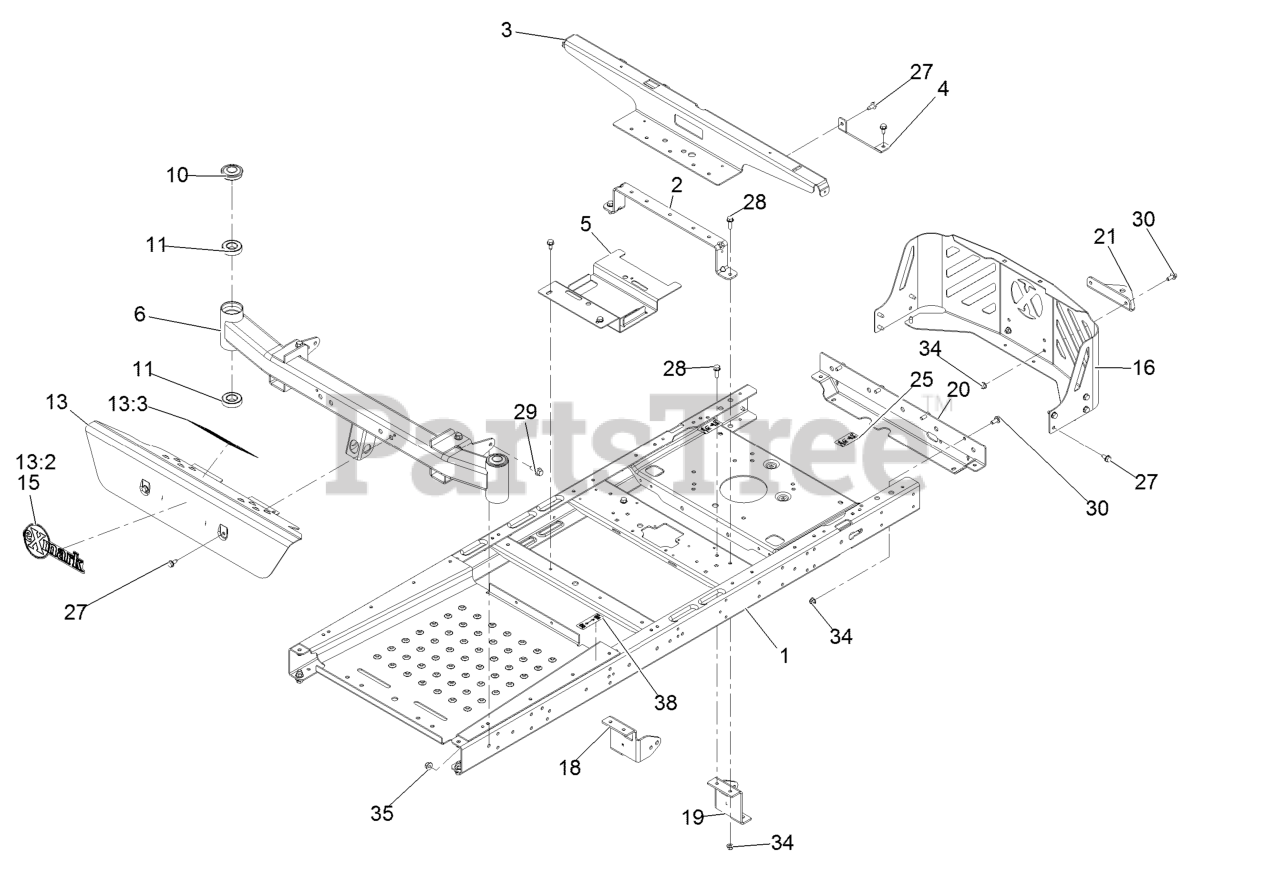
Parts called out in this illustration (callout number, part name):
1	RIVETED FRAME ASM (WIDE LEVER)
2	BRACE-SEAT, REAR (WIDE)
3	SUPPORT-POD
4	SUPPORT-TANK, REAR
5	BRACKET-BATTERY
10	CAP-GREASE
11	BEARING-BALL
13	FOOTREST ASM
13:2	DECAL-EXMARK LOGO
13:3	DECAL-DANGER
15	DECAL-EXMARK LOGO
16	GUARD-ENGINE, WIDE
18	MOUNT-HYDRO, FRONT (RH)
19	MOUNT-HYDRO, FRONT (LH)
20	CROSSMEMBER-REAR, WIDE
21	BRACKET-HITCH
25	DECAL-BYPASS
27	Screw-HWH 5/16-18 X 3/4 Tf
28	SCREW-HHF
29	SCREW-HHF 3/8-16 X 1
30	SCREW-HHF
34	NUT-HF, NI
35	NUT-HF, NI
38	DECAL-BRAKE, PARKING
